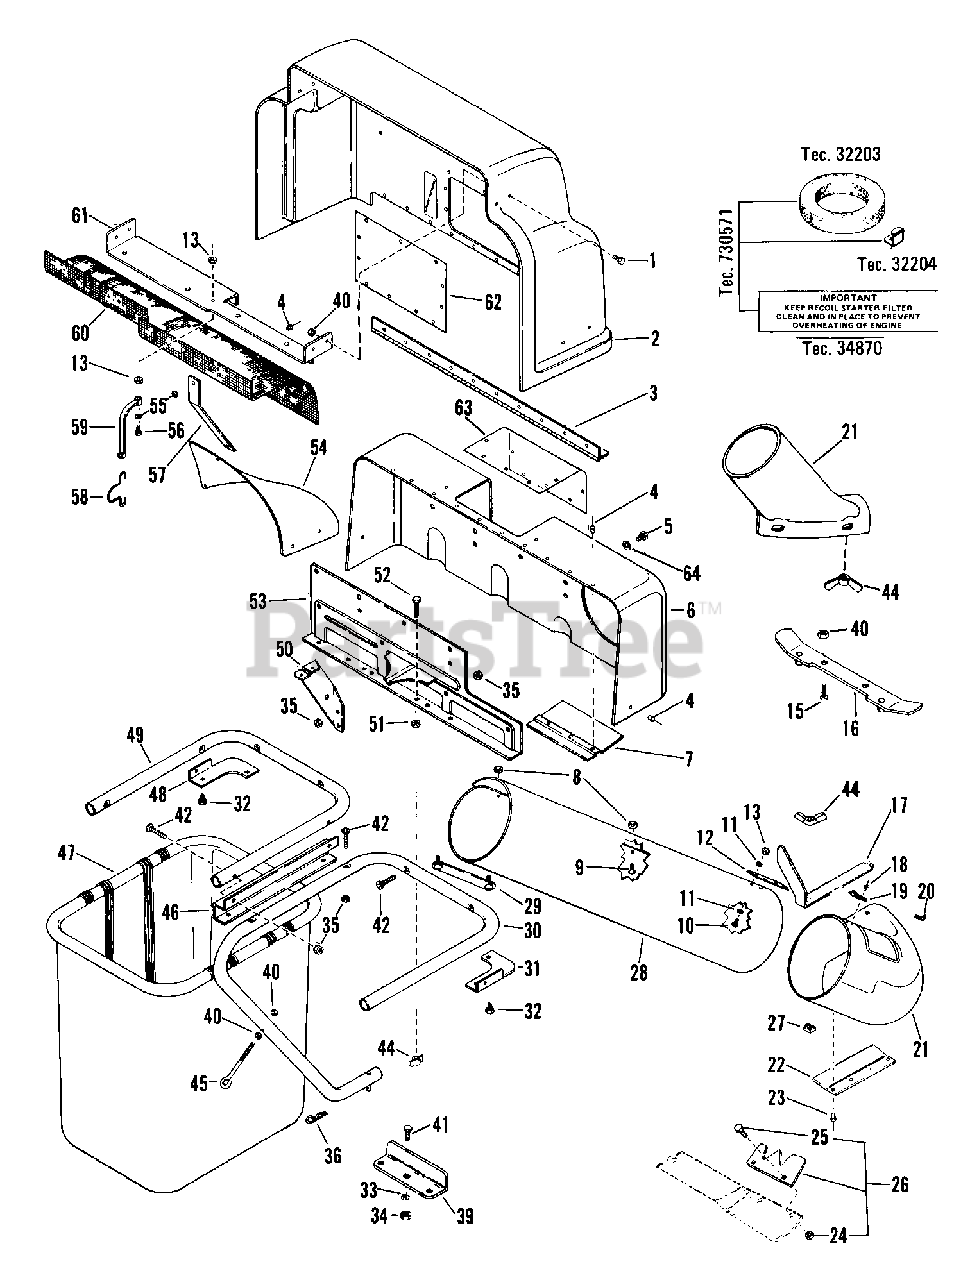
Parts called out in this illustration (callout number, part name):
1	BLT-HEX .25-20X.50 PL GR2
2	HINGED COVER W/DECALS
4	RVT-POP .187X.402 DOME ST
5	SCR-MCH .31-18X.62 SLTR PL
6	STATIONARY COVER
7	TUBE GUIDE
8	NUT-LK-FLG .250-20 PL
9	BLT-RDHDSQNK .25-20X.50 SHT PL
10	SCR-MCH 10-24X.50 SLRH PL
11	WSHR-FL-STL .219X.500X.049 PL
13	NUT-LK TOP 10-24 PL
14	NUT-WING W/INSERT .312 - 18
15	BLT-RDHDSQNK .25-20X1.00 GR5
16	LATCH SPRING
17	BRACKET
18	RVT-TBLR .187X.375 OH ST PL
19	RETAINER
20	PIN-HAIR INT .09X.188 PL
21	BOOT ASSEMBLY 32"
22	EXTENSION CHUTE
23	RVT .187X.343 TR ST PL
24	NUT-LK TOP .312-24 PL GR C
25	BLT-HEX .31-24X.75 GR8
26	SERVICE VANE PACKAGE
27	CLIP CONE
28	28 IN & 32 IN TUBE BLANK
30	RIGHT TUBE
32	SCR-TAP .312-18X.50 HWH PL TR
33	WSHR-LK .500X.151 HVY PL
34	NUT .50-13 PL
35	NUT-LK .312-18 GR A PL
36	PIN-HAIR INT .08X.38X1.42 YWZC
39	BRACKET
40	NUT-LK-CTR .250-20 PL
41	BLT-HEX .50-13X1.00 PL GR2
42	SCR-MCH .31-18X1.50 CROVCNTRS
44	NUT-WING W/INSERT .312 - 18
45	EYEBOLT
46	TUBE BRACKET
47	GRASS BAGGER BASKET
48	LH CORNER BRACKET
49	CENTER TUBE
51	NUT-HEX .312-18
52	BLT-HEX .31-18X1.50 GR2 YWZC
53	MOUNTING BRACKET
55	WSHR-FL-STL .194X.492X.047 PL
56	SCR-MCH 10-24X.88 SLRH PL
59	BATTERY STRAP
61	COVER BRACKET
62	STATIONARY COVER WINDOW
63	STATIONARY COVER
64	WSHR-FL-STL .344X1.125X.063PL
